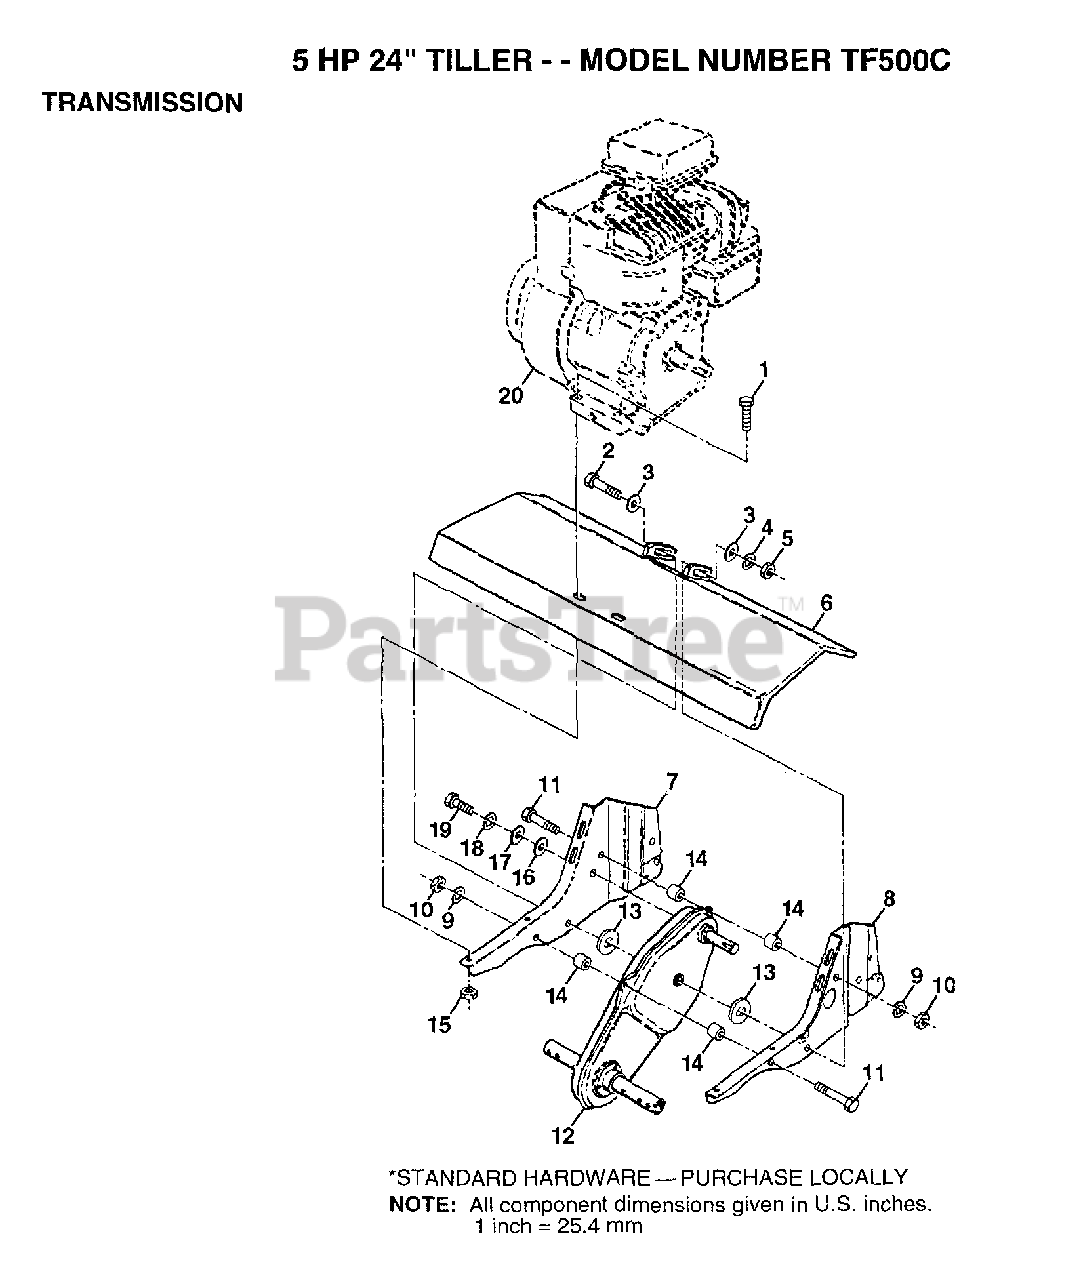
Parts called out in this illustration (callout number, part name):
1	BOLT.HEX.5/16-1.5
2	BOLT.3/8-24X3.75
3	WASHER
4	LOCKWASHER
5	GRIPCO NUT
8	BRACKET.ENG.LH.
9	LOCKWASHER
10	NUT.HEX.5/16-18
14	SPLIT SPACER RT
16	WASHER
17	WASHER
18	LOCKWASHER
19	BOLT
